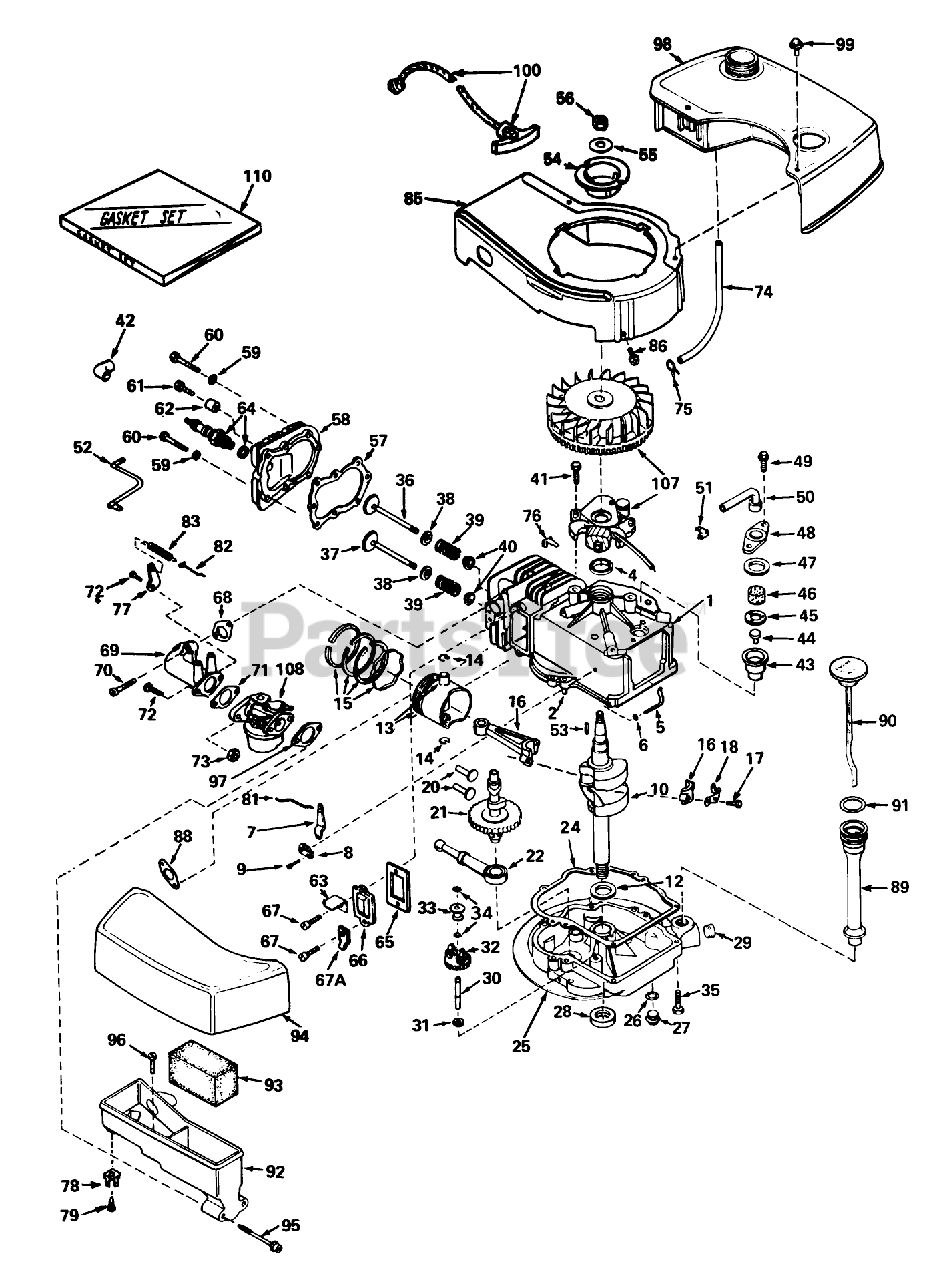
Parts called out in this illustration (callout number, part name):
1	Cylinder Assembly (Incl. Nos. 2, 4 87)
2	Pin-Dowel
4	Seal-Oil
5	Rod, Governor (Incl. No. 36)
6	Washer-Flat
7	Governor Lever
8	Clamp-Lever, Governor
9	Screw
10	Crankshaft
12	Washer-Thrust
13	Piston Pin Assembly (Incl. 2 of No. 14)(Std.)
13	Piston Pin Assembly (Incl. 2 of No. 14)(.010 Oversize)
13	Piston Pin Assembly (Incl. 2 of No. 14)(.020 Oversize)
14	Ring-Retaining, Piston Pin
15	Ring Set-Piston Std.
15	Ring Set-Piston .010 oversize
15	Ring Set-Piston .020 oversize
16	Rod Assembly, Connecting (Incl. Nos. 17 18)
17	Connecting Rod Bolt
18	Plate Lock
20	Lifter-Valve
21	Camshaft(Mech.Comp. Release)
22	Oil Pump ASM
24	Gasket, Mounting
25	Flange Assembly, Mounting (Incl. #27, 28, 29 30)
26	Gasket-Oil Drain
27	Plug Oil Drain
28	Seal-Oil
29	Plug Oil Drain
30	Shaft-Governor
31	Washer-Flat
32	Gear Assembly, Governor
33	Spool, Governor
34	Ring-Retaining
35	Screw (1/4-20 x 1-1/4)
36	Valve, Intake (Incl. Ref. #38, 39 40) (Std.)
36	Valve, Exhaust (1/32" Oversize) (Incl. Nos. 8, 9 10)
37	Valve, Exhaust (Standard) (Incl. Nos. 8, 9 10)
37	Valve, Exhaust (1/32" Oversize) (Incl. Nos. 8, 9 10)
38	Cap-Upper Valve Spring
39	Spring-Valve
40	Cap-Valve, Spring
41	Screw
42	Cover-Spark Plug
43	Body Breather Tube
44	Valve Check
45	2000A37 WIZARD ROTA
46	Element-Breather
47	Gasket-Breather
48	Cover Breather
49	Screw, Hex Hd. w/Conical
50	Tube, Breaker
51	Clip, Breather
52	Wire, Ground
53	Key Flywheel
54	Pulley Starter
55	Washer
56	Hex Nut
57	Oil Fill Tube
58	Head Cylinder
59	Washer
60	Screw
61	Screw Hex Hd. Cap
62	Space
63	Retainer Clip
64	Plug, Spark (J17LM or equiv.)
65	Gasket-Breather
66	Cover-Valve
67	Screw
67A	Terminal
68	Gasket, Intake
69	Pipe, Intake
70	Screw (1/4-20 x 1)
71	Gasket-Carburetor
73	Nut and Lock Washer (1/4-28)
74	Line, Fuel
75	Clamp-Line, Fuel
76	Clip-Wire
77	Lever-Adjusting, R P M
78	Terminal
79	Screw
81	Link Governor
82	Link Governor Spring
83	Spring Governor
85	53024/VAR.GT O/P W/
86	Screw
88	Gasket Exhaust
89	Tube, Oil Filler
90	Dipstick, OiI (Incl. No. 91)
91	O-Ring
92	Body Air Cleaner
93	Filer, Air
94	Cove, Air Cleaner
95	Screw Fil Hd.
96	Screw, Hex Hd.
97	Gasket-Air Cleaner
98	Tank Fuel
99	Screw (10-32 x 35/64)
100	Rope Assy., Starter
107	Magneto
108	Carburetor
110	53024/VAR.16HP O/P
